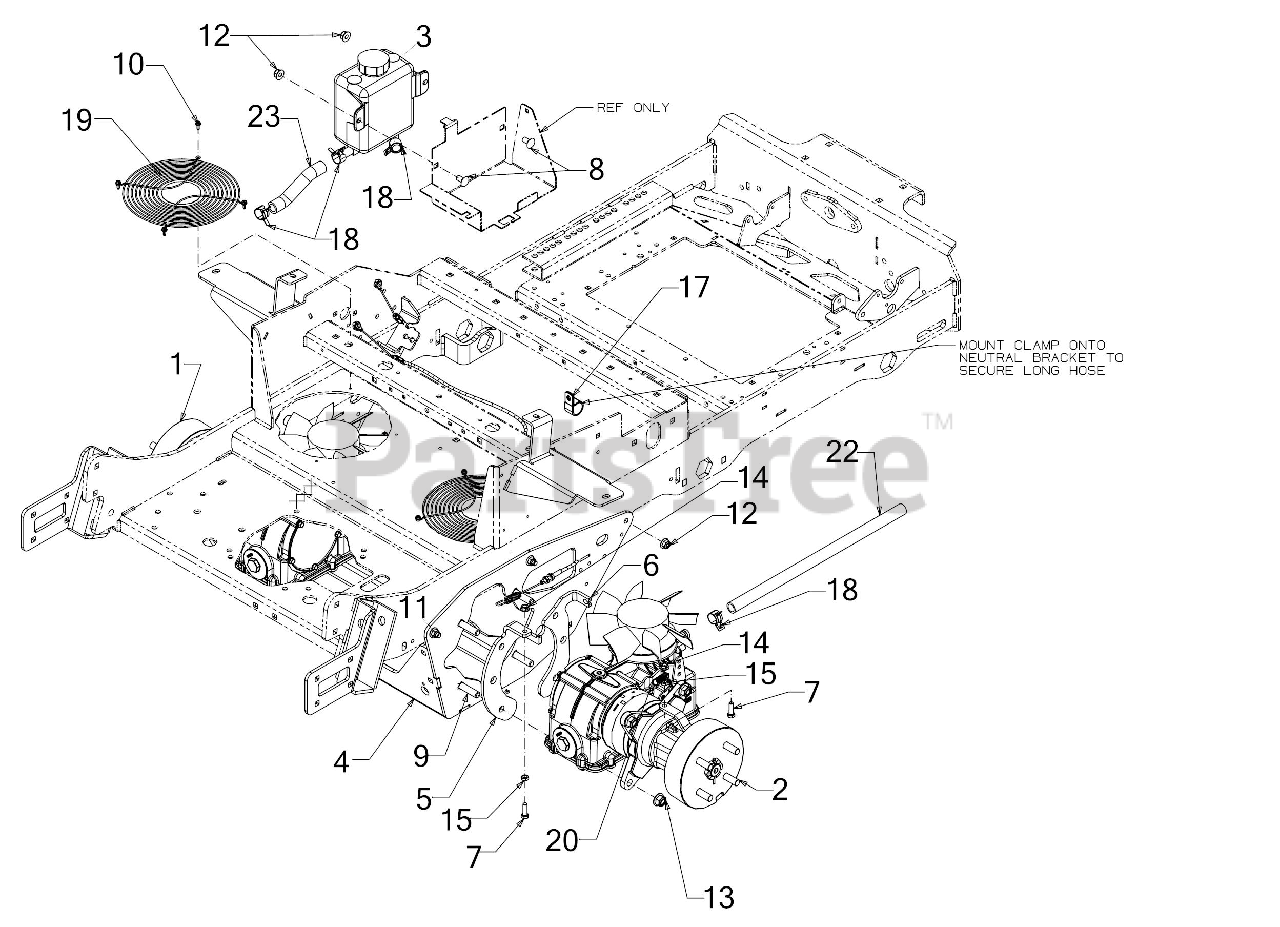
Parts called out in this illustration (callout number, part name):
1	TRANSMISSION ASSEMBLY PARKER (LH)
2	TRANSMISSION ASSEMBLY PARKER (RH)
3	HYDRO TANK ASSEMBLY
4	TRANSMISSION MOUNTING BRACKET ASSEMBLY
5	BRAKE SPRING MOUNTING BRACKET
6	BRAKE CABLE MOUNTING BRACKET
7	SCREW 5/16-18 x 1.0 GR5
8	CARRIAGE BOLT 3/8-16 x .750 GR5
9	CARRIAGE BOLT 1/2-13 GR5
10	SCREW 10-24 x 0.500
11	CARRIAGE BOLT 3/8-16 X1.25 GR5
14	HEX FLANGE NUT
17	HOSE CLAMP 1.0"
18	HOSE CLAMP
20	EXTENSION SPRING .500 OD x 1.71
22	OIL HOSE 5/8 ID X 18.00 LG
